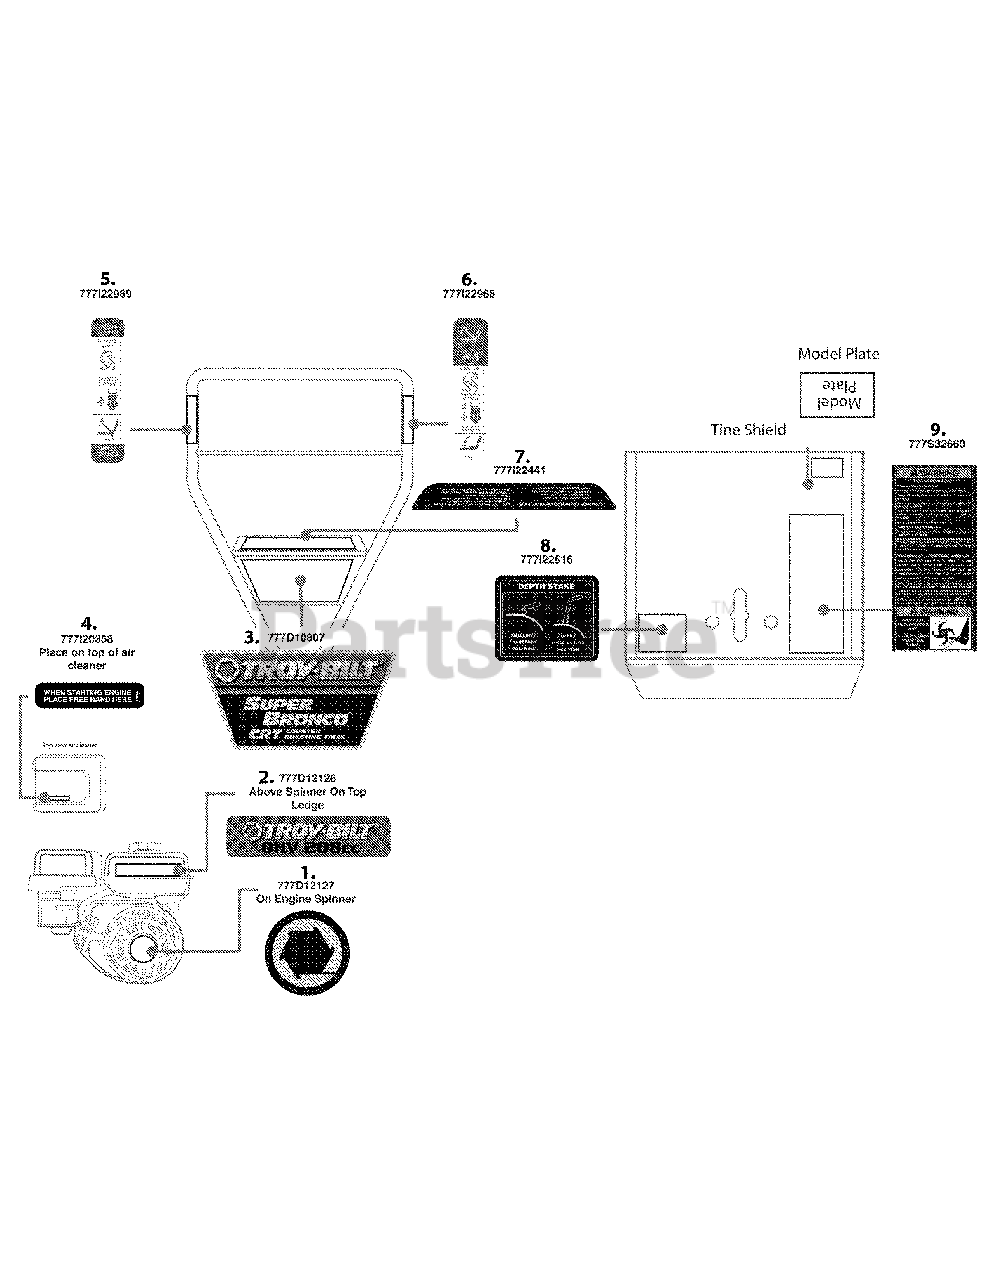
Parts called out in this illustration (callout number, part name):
1	LABEL-TILLER MTD ENGINE
2	LABEL-TILLER MTD ENGINE TROY
3	LABEL-TILLER HANDLE TROY CRT
4	LABEL-PLACE HAND HERE
5	LABEL-TILLER 650 HANDLE/RGHT REV
6	LABEL-TILLER 640/650 HANDLE
7	LABEL-HNDL PNL INST CRT SPR BRONCO
8	LABEL:TILLER TINE SHIELD DEPTH
9	LABEL:TILLER TINE SHIELD
